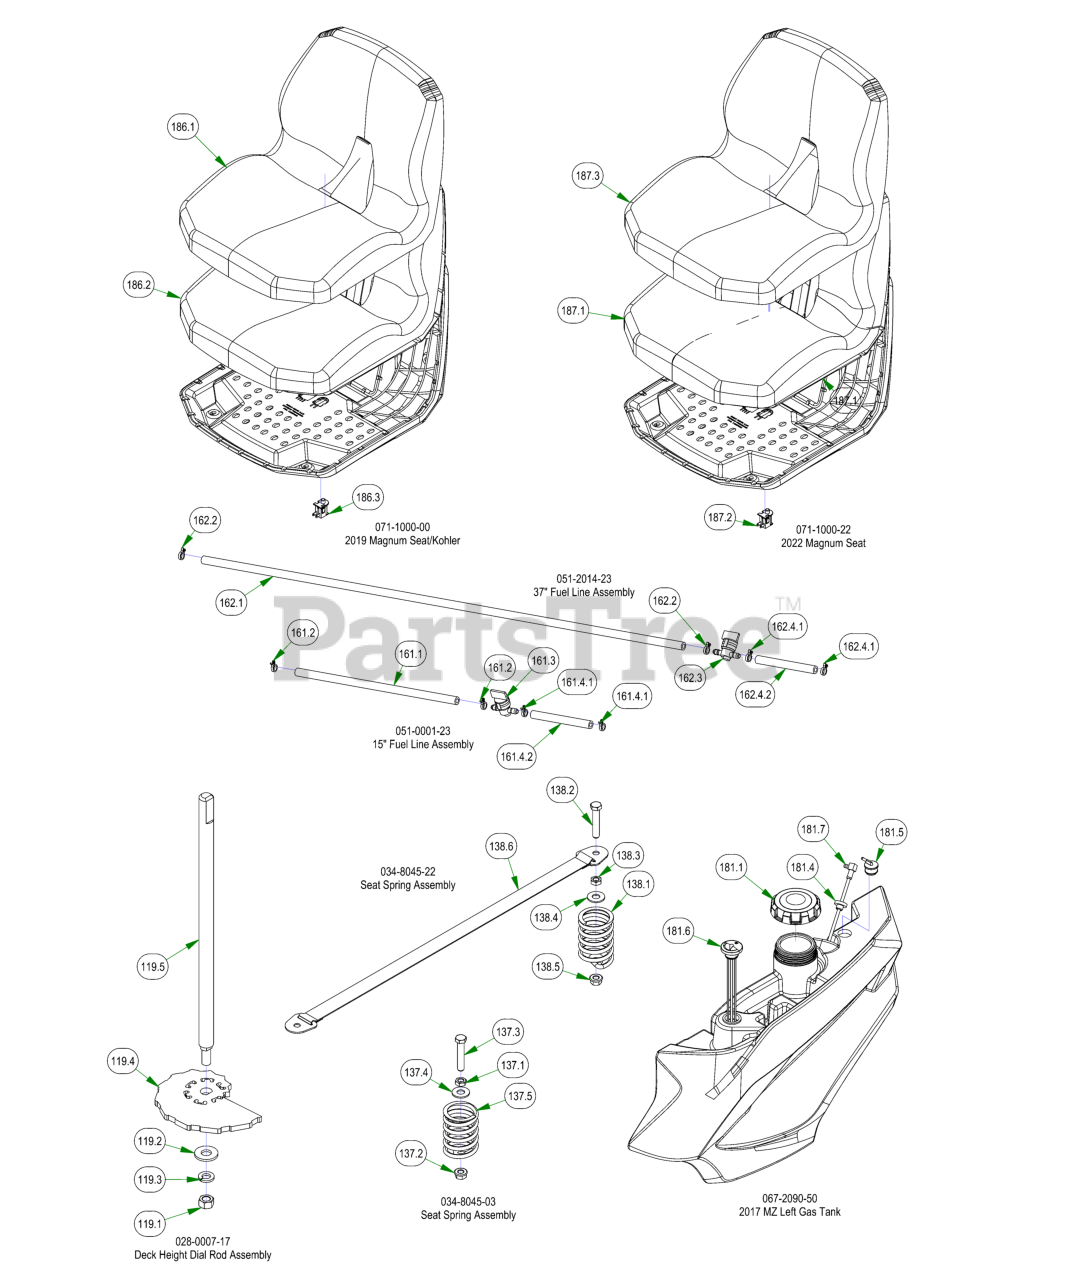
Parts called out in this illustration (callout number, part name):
119	Deck Height Dial Rod Assembly
119.1	3/8" Fine Threaded Jam Nut
119.2	3/8" Flat Washer
119.3	3/8" Lock Washer
119.4	2017 MZ/ZT Cam Plate
119.5	2017 Deck Height Dial Rod MZ
137	Seat Spring Assembly
137.1	3/8-16 Half Jam Nut
137.2	3/8-16 HEX SERRATED FLANGE NUT HARD/ZINC
137.3	3/8-16 X 2 HEX CAP SCREW (GR.5) ZINC
137.4	3/8 FLAT WASHER USS (1" OD) ZINC
137.5	Seat Spring
138	Seat Spring Assembly
138.1	Seat Spring
138.2	3/8-16 X 2 HEX CAP SCREW (GR.5) ZINC
138.3	3/8-16 Half Jam Nut
138.4	3/8 FLAT WASHER USS (1" OD) ZINC
138.5	3/8-16 HEX SERRATED FLANGE NUT HARD/ZINC
138.6	Seat Strap with Buckles
161	15" Fuel Line Assembly
161.1	11" 1/4 Fuel Line
161.2	1/4 Fuel Hose Clamp
161.3	2 Way Fuel Shut-Off Valve
161.4	Fuel Line 4" Section with Clamps
161.4.1	1/4 Fuel Hose Clamp
161.4.2	4" 1/4 Fuel Line
162	37" Fuel Line Assembly
162.1	37" 1/4 Fuel Line
162.2	1/4 Fuel Hose Clamp
162.3	2 Way Fuel Shut-Off Valve
162.4	Fuel Line 4" Section with Clamps
162.4.1	1/4 Fuel Hose Clamp
162.4.2	4" 1/4 Fuel Line
181	2017 MZ Left Gas Tank
181.4	Pick-Up Grommet
181.5	Rollover Valve W/Grommet
181.6	Fuel Gauge w/Grommet
186	2019 Magnum Seat/Kohler
186.1	Seat Cover for 071-1000-00
186.2	Seat Foam for 071-1000-00
186.3	SeatSwitch for 071-1000-00/071-1000-22/071-2100-22
187	2022 Magnum Seat
187.1	SK120 Seat Foam for 071-1000-22
187.2	SeatSwitch for 071-1000-00/071-1000-22/071-2100-22
187.3	Bad Boy SK120 Cover with Logo for 071-1000-22
